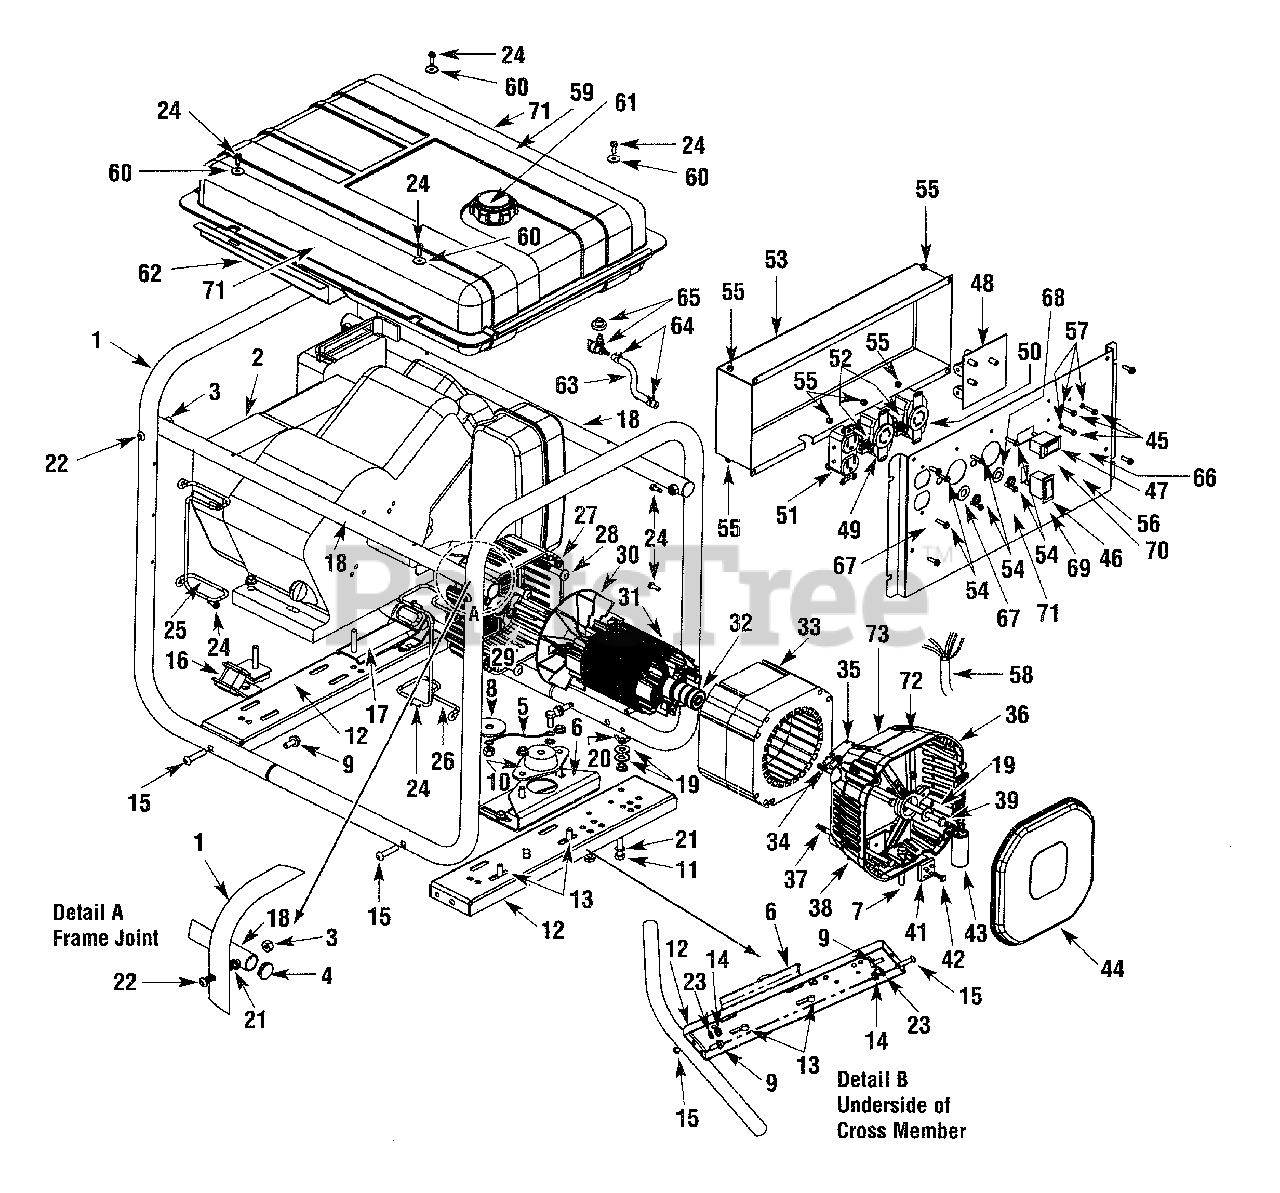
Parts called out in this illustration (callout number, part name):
1	Carry frame with box
2	9 HP gasoline engine
3	Nut, 5/16" -18 Nyloc
4	Plug, 1" round endcap
5	Grounding wire, 5-3/4"
6	"C" mounting bracket
7	Bolt, 5/16" -18 x 2-1/2" HH
8	Flat washer, 2" OD
9	Screw, 5/16" -12 x 3/4" thread forming
10	Vibration isolator
11	Bolt, 5/16" -18 x 1-1/4" HH
12	Crossmember, bolt on
13	Bolt, 5/16" -18 x 3/4" HH
14	Nut, 5/16" serrated flange
15	Screw, 5/16" -18 x 1-1/2" SBC
16	Isolator, angled mount
17	Isolator, extended angled mount
18	Mount, cross bar-gas tank
19	Flat washer, 5/16"
20	Wing nut, 5/16" -18
21	Washer, 5/16" external tooth
22	Bolt, 5/16" 18 x 2-1/4" SBC
23	Washer, 5/16" split-ring lock
24	Screw, #10 self tapping
25	Holder, engine end mount cord
26	Holder, alternator end mount cord
27	Adapter, engine
28	Screw, 3/8" -16 x 3/4" button socket
29	Screw, No. 8 -18 x 5/8"
30	Fan, rotor
31	Assembly, rotor
32	Bearing, rotor
33	Assembly, stator
34	Kit, brush
35	Holder, brush
36	Endbell, bearing
37	Bolt, 1/4" x 20 hex
38	Screw, 18 Hi-Lo
39	Bolt, 5/16" x 24 hex
41	Rectifier, 200V, 8 Amp
42	Screw, #10 self tapping type "F"
43	Assembly, 220uF capacitor
44	Cover, end
45	Screw, #6 - 32 X 1/4" pan head
46	Switch, idle control on-off
47	Switch, full power on-off
48	Board, idle control circuit
49	Receptacle, 120V - 30A
50	Receptacle, 120/240V - 20A
51	Receptacle, 120V -15A
52	Breaker, circuit
53	Cover, power panel rear
54	Bolt, #8 - 32 hex head
55	Nut, #8 - 32 Nyloc hex
56	Panel, power control
57	Washer, #6 lock
58	Harness, electrical wiring
59	Tank, fuel
60	Washer, fuel tank mounting
61	Cap, fuel tank
62	Shield, heat
63	Line, fuel
64	Clamp, fuel line
65	Kit, fuel valve
66	Decal, warning control
67	Decal, 120V black
68	Decal, 120V/240V black
69	Decal, idle control
70	Decal, full power control
71	Decal, tank
73	Decal, Model
